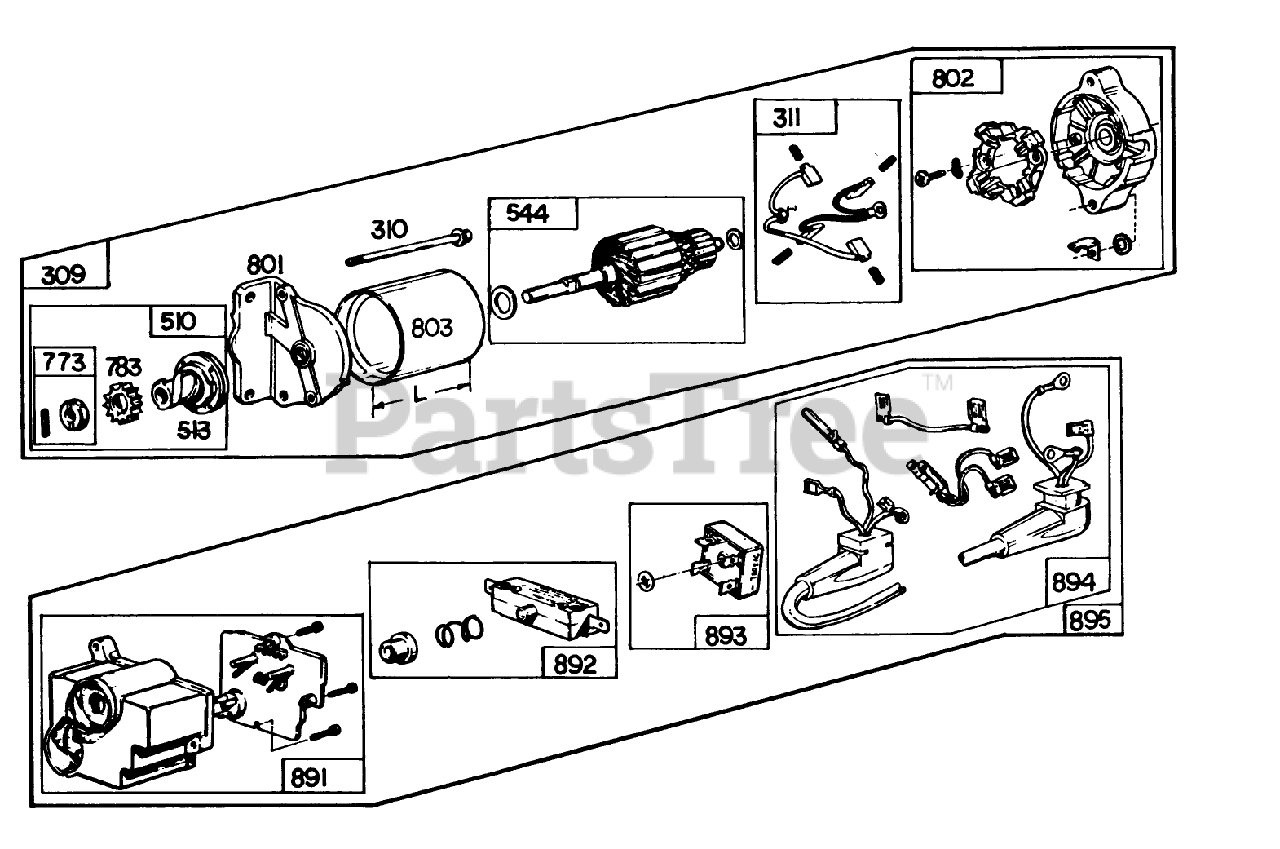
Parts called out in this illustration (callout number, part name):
309	Motor Drive Assembly
310	Thru Bolt Assembly
311	Brush Assembly
510	Drive Assembly
513	Clutch Assembly
544	Armature Assembly
773	Gear-Starter
801	Drive End Cap Assembly
802	Comm. End Cap Assembly
803	Housing Assembly
891	Housing Group
892	Switch Group
893	Rectifier
894	Lead Group
895	Control Group
